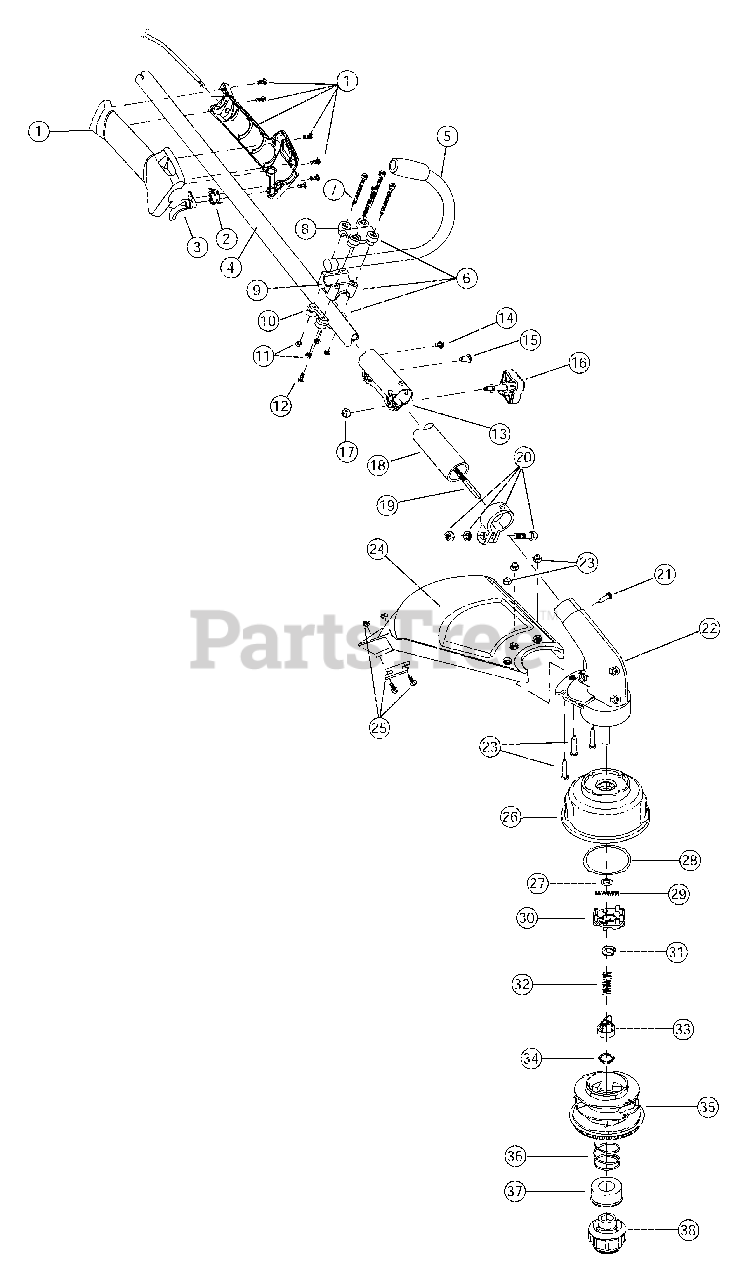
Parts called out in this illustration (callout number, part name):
1	Throttle Housing Assembly
2	Throttle Trigger Spring
3	Throttle Trigger
4	Upper Drive Shaft Housing Assembly
5	J-Handle Assembly
6	Handle Bracket Assembly
8	Upper Handle Clamp
9	Middle Handle Clamp
10	Lower Handle Clamp
12	Anti-Rotation Screw
13	Split Boom Coupler
16	Adjustment Knob
17	Knob Retaining Nut
18	Lower Drive Shaft Housing Assembly
19	Lower Flexible Drive Shaft
20	Lower Clamp Assembly
21	Anti-Rotation Screw
22	Gearbox Assembly
23	Shield Mounting Hardware
24	Shield Assembly
25	Blade Assembly
26	Outer Spool Assembly
27	Retainer
28	Thrust Washer
29	Small Spring
30	Slider
33	Plunger
35	Inner Reel
36	Large Spring
37	Foam Seal
38	Bump Head Knob Assembly
